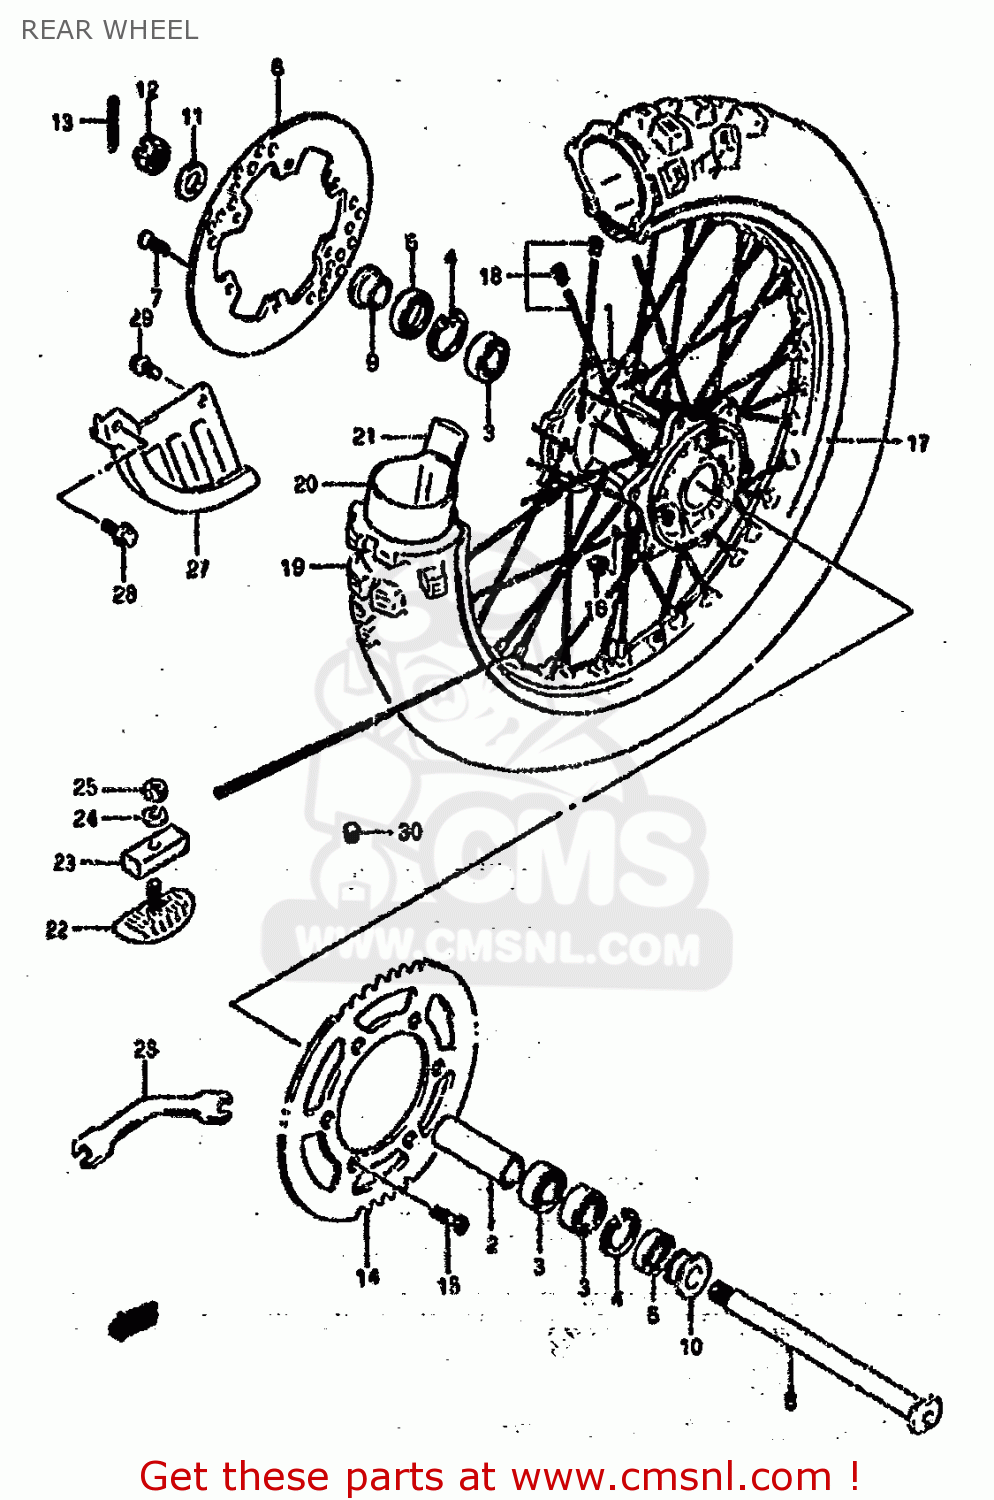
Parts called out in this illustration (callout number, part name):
1	HUB,RR WHEEL
2	SPACER,RR HUB BEARING
3	BEARING
4	CIRCLIP
5	SEAL,DUST
6	DISC,RR BRAKE
7	SCREW,BRAKE DISC
8	AXLE,RR
9	SPACER,RR AXLE,R
10	SPACER,RR AXLE
11	WASHER(19X32X3.2)
12	NUT
13	PIN,COTTER
14	SPROCKET,REAR
15	BOLT(8X30.5)
16	NUT
17	RIM,RR WHEEL(2.15X19 AL)
18	SPOKE SET,RR WHEEL
19	TIRE
20	TUBE ASSY,WHEEL INNER
21	PROTECTOR
22	STOPPER,BEAD(2.15)
23	CUSHION,BEAD STOPPER
24	WASHER
25	NUT
26	SPANNER,OPEN
27	COVER,REAR DISC
28	BOLT
29	BOLT
30	CAP(OD:12)
